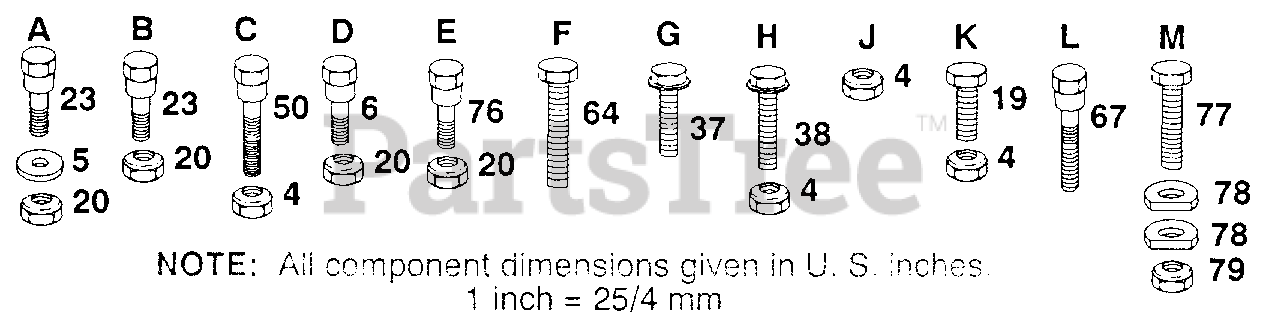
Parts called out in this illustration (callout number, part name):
5	WASHER M
6	BOLT
23	BOLT
37	SCREW
38	SCREW
50	BOLT
64	BOLT
67	BOLT.3/8-14X1.25
77	BOLT LT
78	WASHER T
